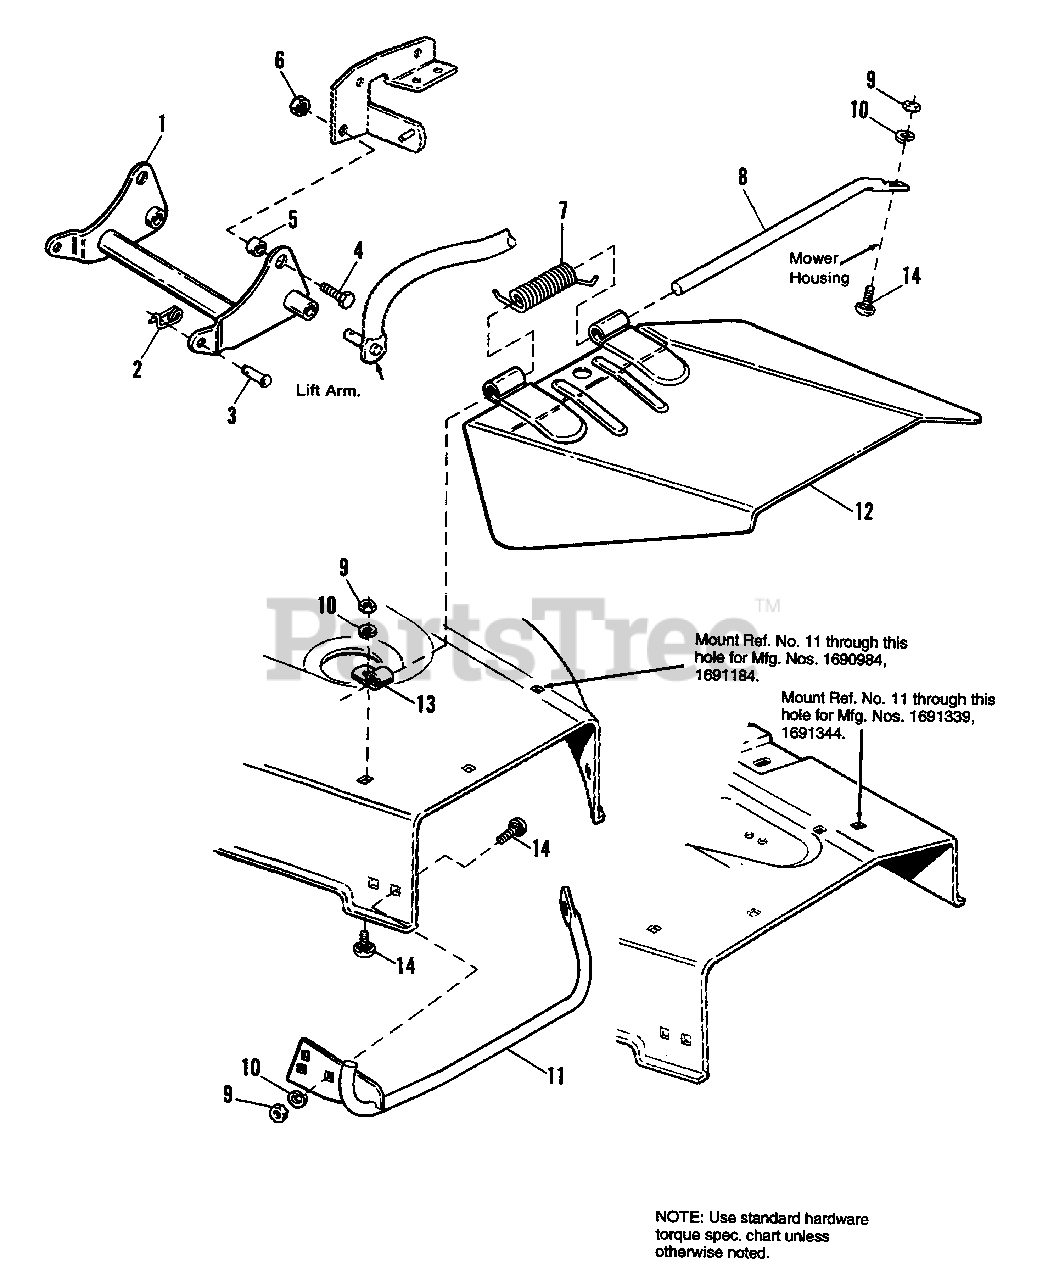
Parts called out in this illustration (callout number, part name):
1	ARM ASSY., Rocker
2	CLIP, Pin, Safety
3	PIN, 3/8 x 1-1/2
4	CAPSCREW, Hex, 1/2-13 x 1-1/4
6	NUT, Hex, Centerlock, 1/2-13
7	SPRING, Torsion
8	ROD, Hinge
9	NUT, Hex, 3/8-16
10	LOCKWASHER, 3/8
11	STONE GUARD ASSY.
12	DEFLECTOR ASSY.
13	BRACKET, Hinge
14	BOLT, Carriage, 3/8-16 x 1
